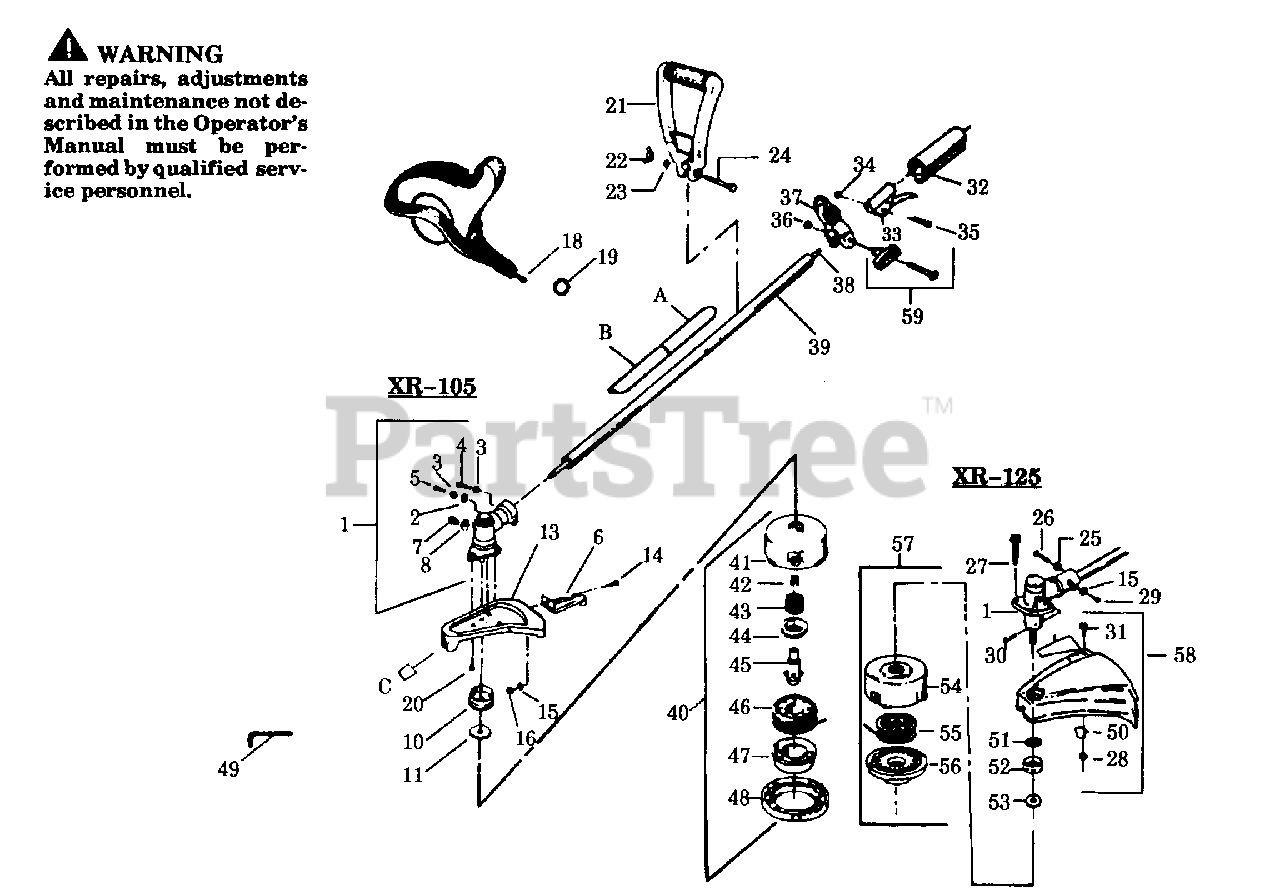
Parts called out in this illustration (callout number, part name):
1	XR-125
3	Lockwasher
6	Line Limiter
10	Upper Adaptor
11	Lower Adaptor
18	Shoulder Strap
19	Shoulder Strap Key Ring
21	Assist Handle
22	Wing Nut "D" Handle
25	Lockwasher
27	Screw
28	Nut
32	Drive Shaft Hsg. Grip
33	Throttle Control Ass'y.
37	Clamp Harness Ass'y.
40	Cutting Hd. Ass'y. (Inc.#41-48) XR-105
41	Hub w/ Line Saver
42	Line Saver
43	Spring
44	Spring Adaptor
45	Drive Gear
46	Spool w/Line
47	Release Button
50	Line Limiter
52	Dust Cup
53	Grass Washer
54	Hub Ass'y.
55	Spool w/Line
57	Cutting Head Ass'y. (Inc. #54- 56)-Model XR-125
58	Shield Kit Ass'y.
59	"T" Handle Kit
A	Safety Label Decal (Upper)
B	Safety Label Decal (Lower)
C	Shield Warning Decal
